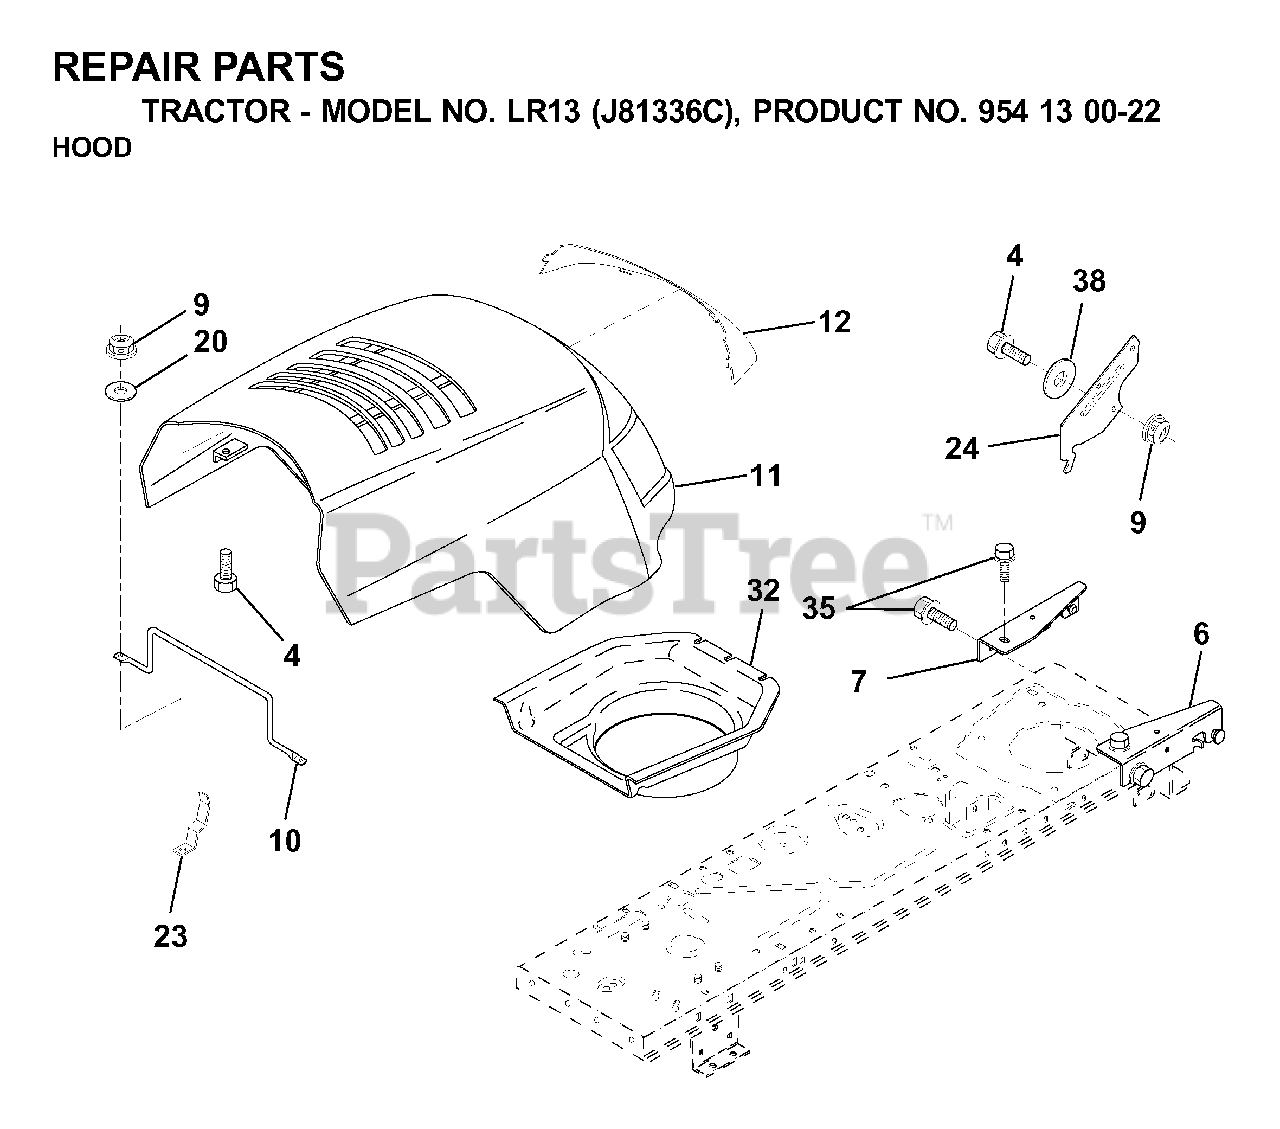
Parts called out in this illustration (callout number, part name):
4	BOLT
6	BRACKET ASSY HOOD
7	BRACKET ASSY
9	LOCKNUT
20	WASHER
23	HOOD LATCH
35	SCREW
